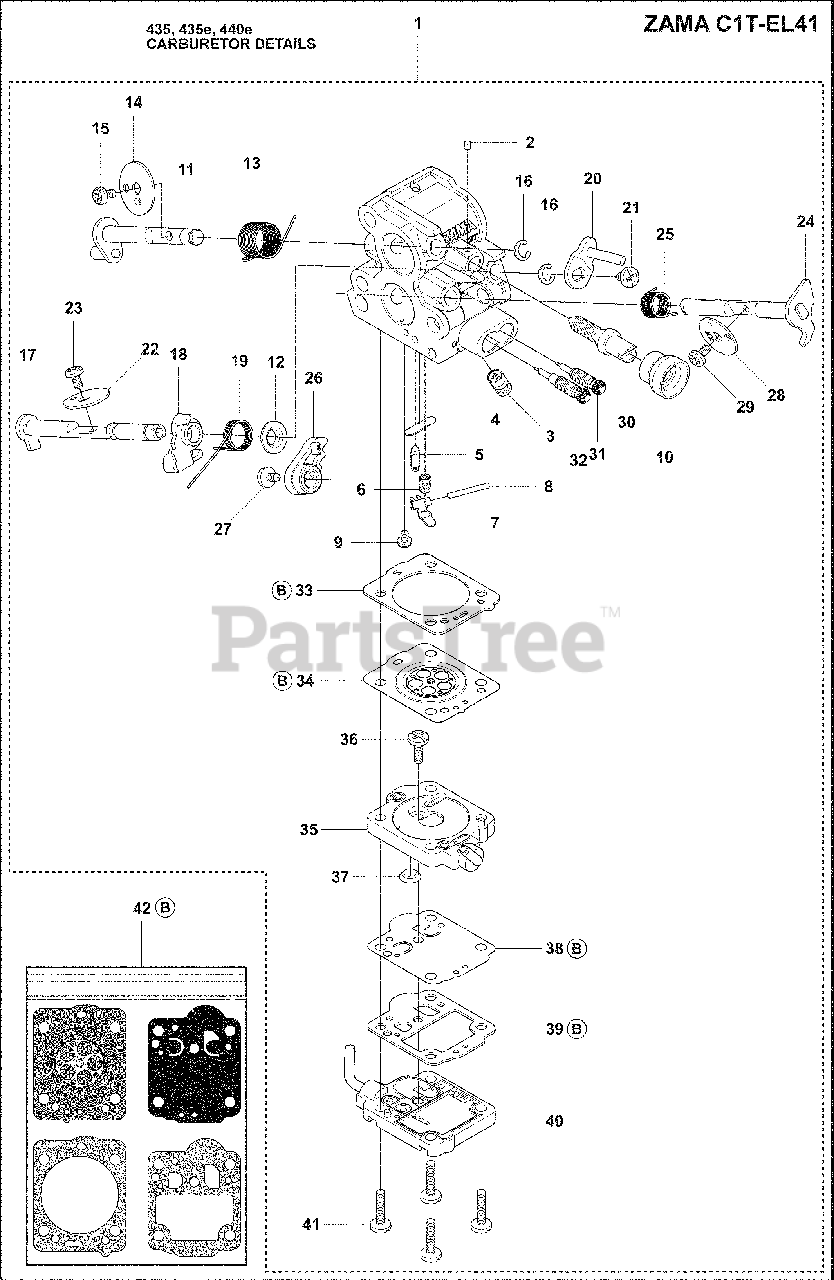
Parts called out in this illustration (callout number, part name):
1	Carburetor
2	Plug
3	Nozzle Assembly
4	PLUG
5	Inlet Needle
6	Spring
7	Lever
8	Pin
9	SCREW
10	CAP ZAMA 0051034
11	SHAFT ASSY
12	COLLAR ZAMA 005020
13	Spring
14	VALVE
15	Screw
16	Circlip
17	Shaft Assembly
18	Lever
19	Spring
20	Lever
21	Screw
22	VALVE
23	Screw
24	Shaft Assembly
25	Spring
26	Throttle Control Lever
27	Screw
28	VALVE
29	Screw
30	Screw
31	Screw
32	Screw
33	Metering Gasket
34	Diaphragm
35	BODY
36	Screw
37	STRAINER
38	Diaphragm
39	Pump Gasket
40	Cover
41	Screw
42	Carburetor Gasket Kit
